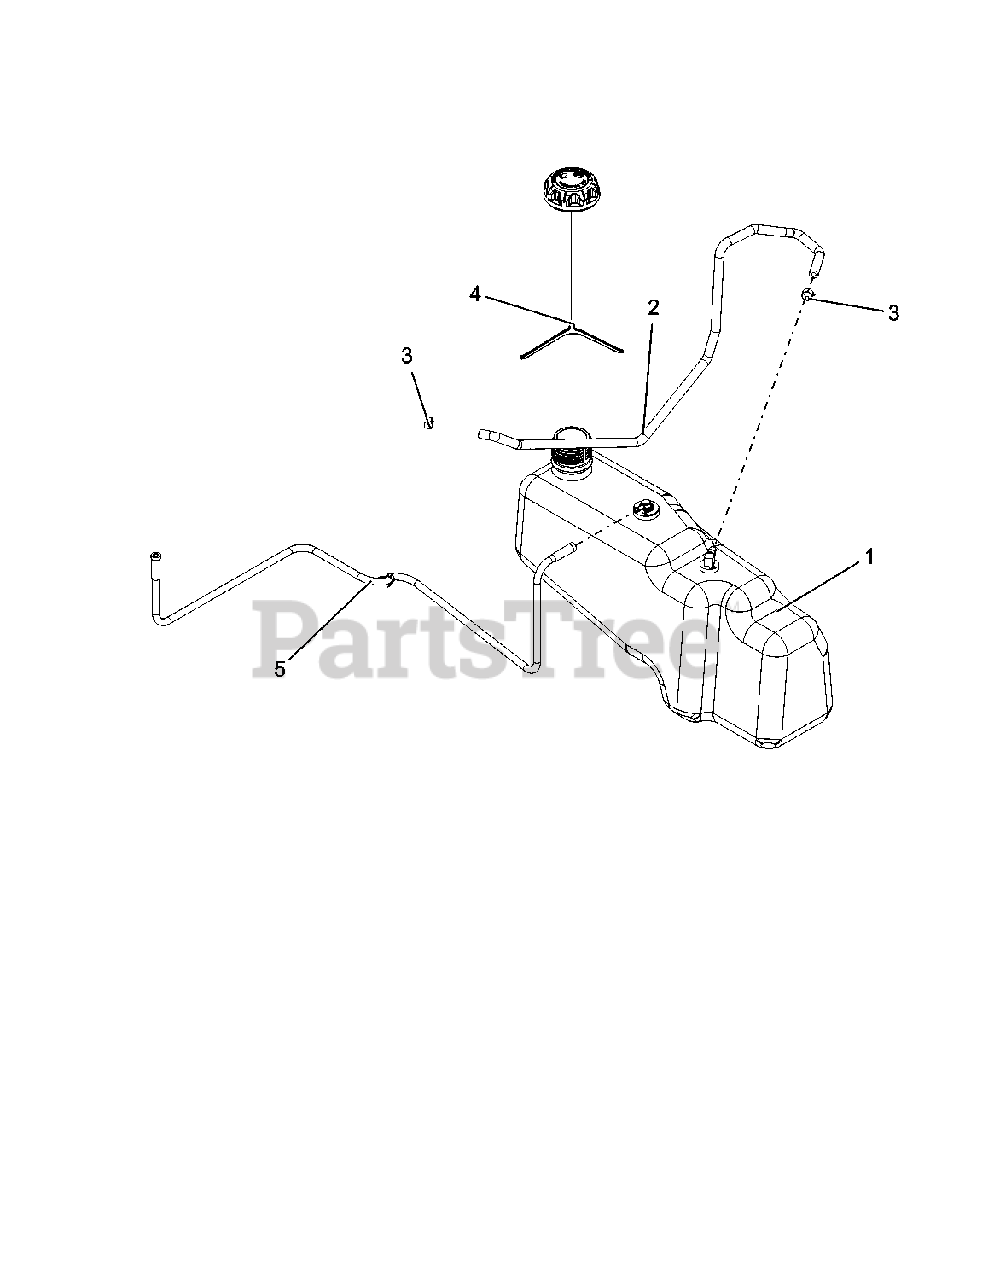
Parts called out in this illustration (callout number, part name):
1	ASM,TANK NON-PERM FUEL
2	HOSE, .25 LOW-PERM BULK GAS
3	CLAMP, FUEL LINE
4	CAP, FUEL VENT-IN 2.25" RATCH.
5	LINE, FUEL VENT KOHLER
